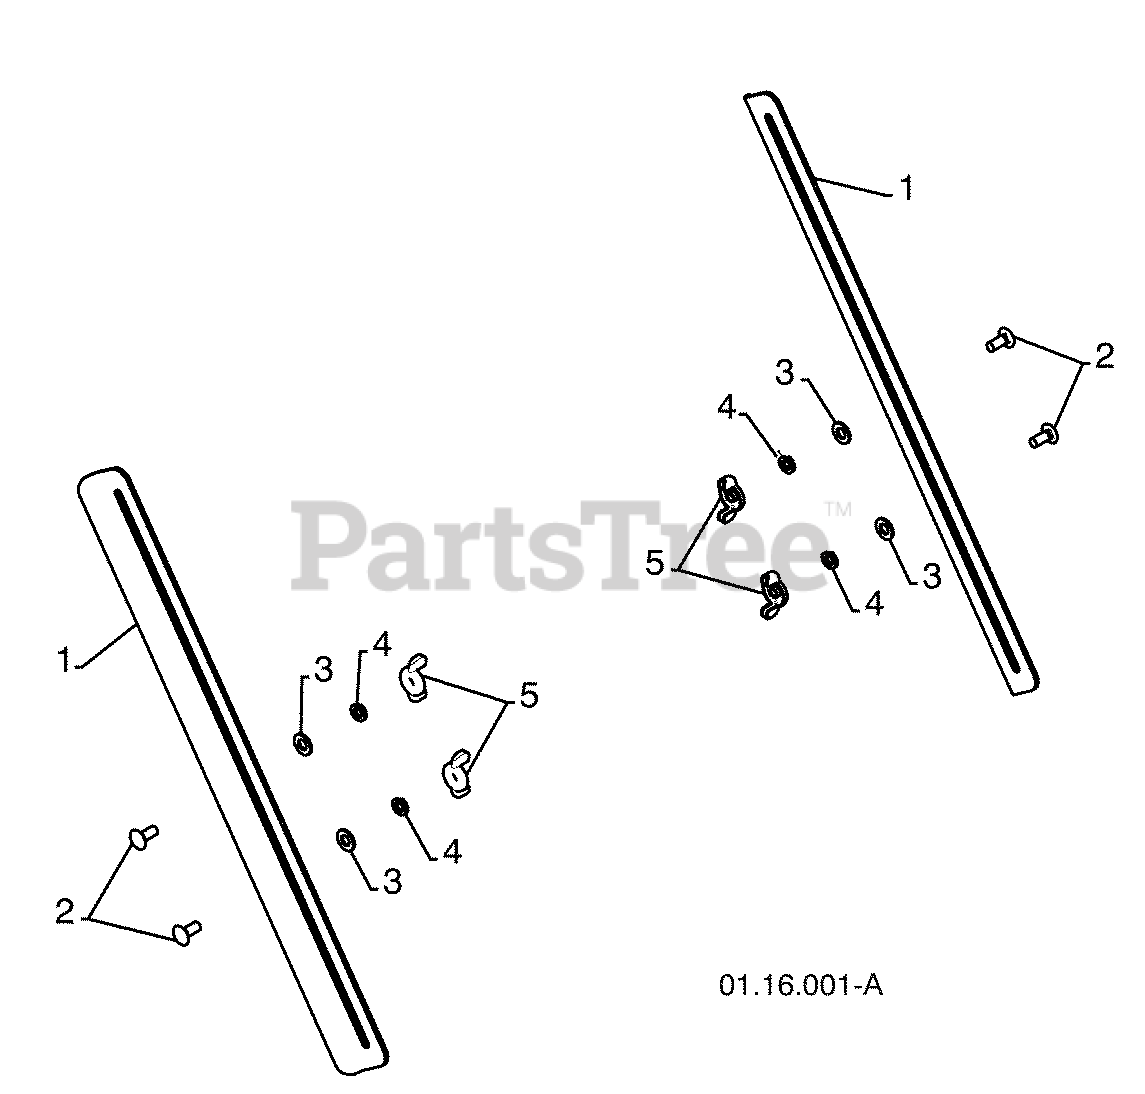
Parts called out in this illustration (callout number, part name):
1	DRIFT CUTTER BAR
2	CARRIAGE BOLT 5/16-18 X .750
3	PLASTIC WASHER
4	LOCKWASHER 5/16
5	NUT 5/16-18
